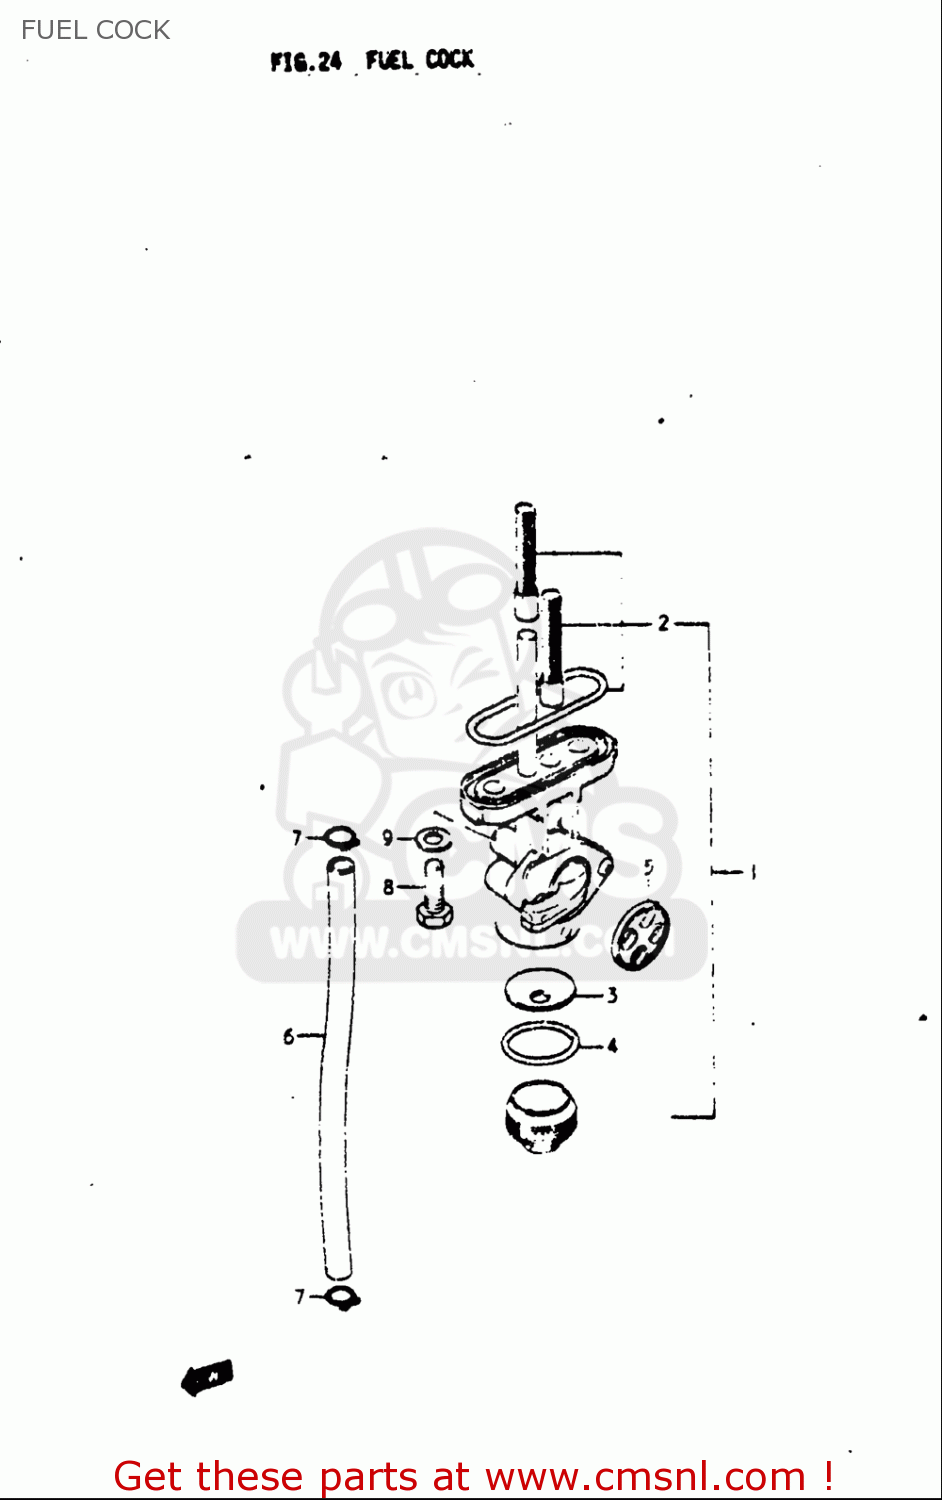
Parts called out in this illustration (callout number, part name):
1	COCK ASSY,FUEL
2	FILTER SET,FUEL COCK
3	NET,STRAINER
4	GASKET,FILTER (NAS)
5	GASKET,LEVER (NAS)
6	HOSE(5X8.2X2000)
7	CLIP
8	BOLT(6X20)
9	GASKET(5.8X13X1.2) (NAS)
